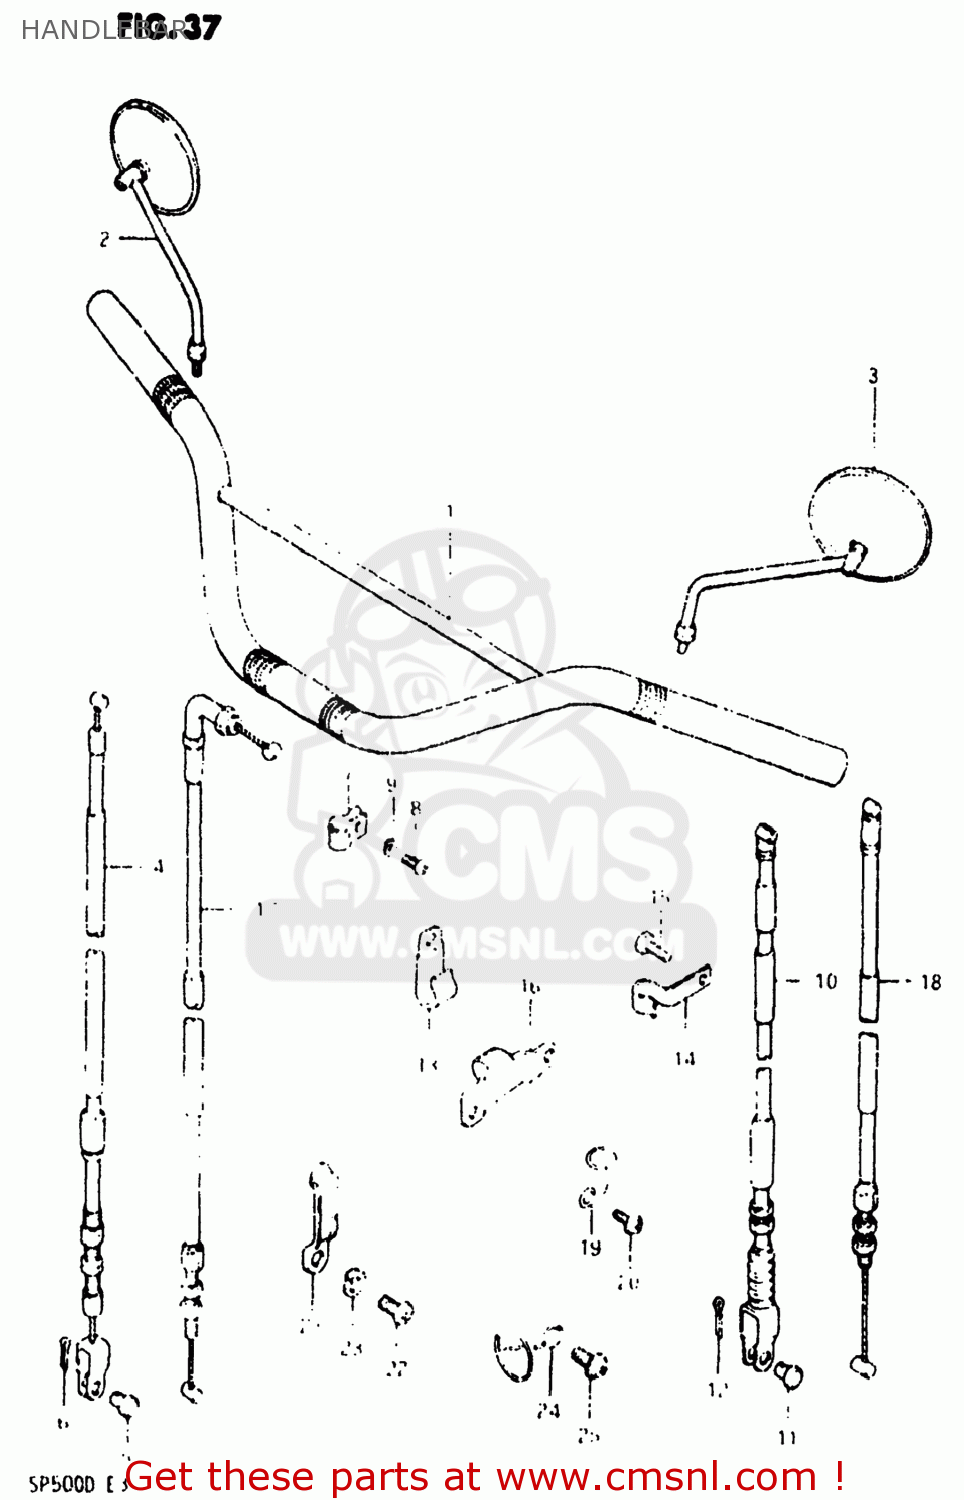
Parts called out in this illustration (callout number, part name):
1	HANDLEBAR
2	MIRROR ASSEMBLY,RIGHT
3	MIRROR ASSEMBLY,LEFT
4	CABLE ASSEMBLY,FRONT BRAKE
5	PIN(L:17.5)
6	PIN
7	GUIDE,CABLE
8	SCREW
9	LOCK WASHER
10	CABLE ASSEMBLY,CLUTCH
11	PIN(L:15)
12	PIN
13	CLAMP
14	CLAMP,CLUTCH CABLE NO.1
15	BOLT
16	STOPPER,CLUTCH CABLE
17	CABLE ASSY,THROTTLE
18	CABLE ASSY,DECOMP
19	GUIDE
20	SCREW
21	CLAMP
22	SCREW
23	LOCK WASHER
24	GUIDE,CABLE
25	SCREW
